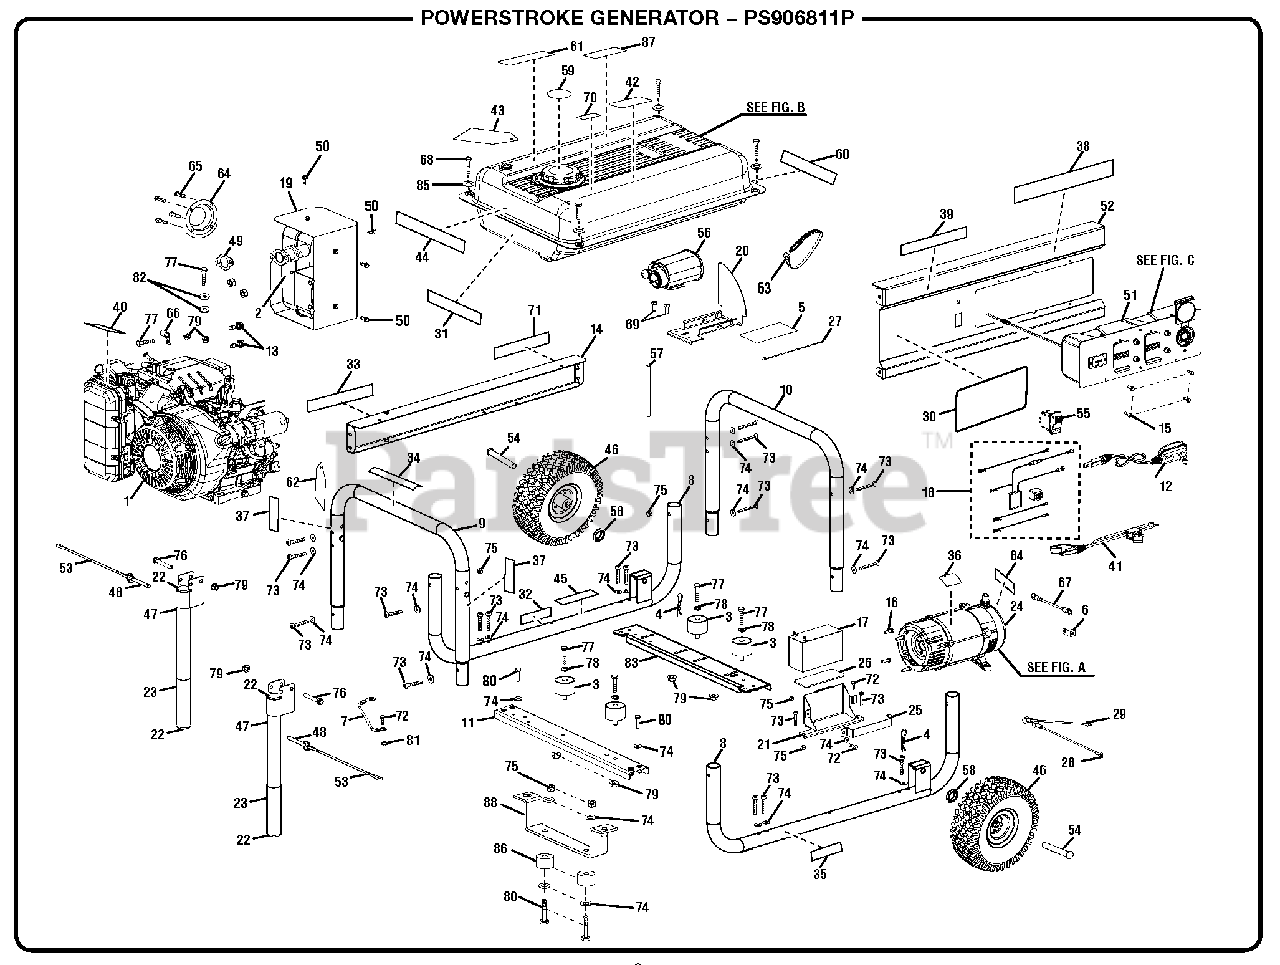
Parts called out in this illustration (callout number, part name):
1	Engine (Honda)
2	Muffler
4	Hitch Pin
5	Rubber Sheet
6	Ground Lug
7	Ground Wire Assembly
8	Lower Frame Assembly
9	Tube Assembly (Left)
10	Tube Assembly (Right)
11	Cross Brace (Engine)
12	Battery Charger
13	Bolt (5/16-24 x 5/8 in.)
14	Back Panel
15	Screw (6-20 x 3/8 in.)
16	Bolt (3/8-16 x1.25 in.)
17	Battery
18	Wire Harness
19	Heat Shield
20	Bracket (Carbon Canister)
21	Battery Box Gasket
23	Handle Grip
24	Generator Head w/AVR
25	Battery Hold Down Bracket
26	Gasket (Battery Hold Down Bracket)
28	Battery Cable (Red)
29	Battery Cable (Black)
30	Logo Label
31	Electric Start Label
32	Hot Surface Label
33	Danger Label
34	Fire Danger Label
35	Engine Lubricant Label
36	Data Plate Label
37	Locking Pin Label
38	Honda Label
39	Electric Start Label
40	Choke Label
41	Pigtail (DC)
42	Fuel Warning Label
43	Danger Hang Tag
44	Inquires Label
45	Combustion Warning Label
47	Handle Assembly
48	Release Pin (5/16 x 2 in.)
50	Bolt (M6 x 9 mm)
51	Panel Assembly
52	Front Panel
55	Start Switch w/Lock
56	Carbon Canister Assembly
57	Purge Hose
58	Washer (1/2 in.)
59	Fuel Stabilizer Label
60	Ground Warning Label
61	Fuel Stabilizer Label (Sp)
62	Hang Tag (Eng/Sp)
63	Cable Tie
64	Spark Arrestor
65	Screw (8-32 x 3/8 in., Pan Hd.)
66	J-Clamp (1/2 in.)
67	Bonding Wire
68	Screw (1/4-14 x 1-1/4 in.)
69	Screw (#10-16 x 3/4 in.)
70	E85 Label
71	Fire Distance Label
72	Screw (M6 x 16 mm, Hex Hd.)
73	Screw (M6 x 50 mm, T30, Pan Hd)
74	Washer (M6)
75	Lock Nut (M6)
76	Bolt (M8 x 55 mm, Hex Hd.)
77	Bolt (M8 x 35 mm, Hex Hd.)
78	Washer (M8)
79	Flange Nut (M8)
80	Bolt (M6 x 25 mm, Hex Hd.)
81	Star Washer (M6)
82	Washer (5/16 in)
83	Cross Brace (Generator Head)3
84	Ground Label
85	Washer (1/4 in.)
87	CPSC Label
88	Foot Bracket
